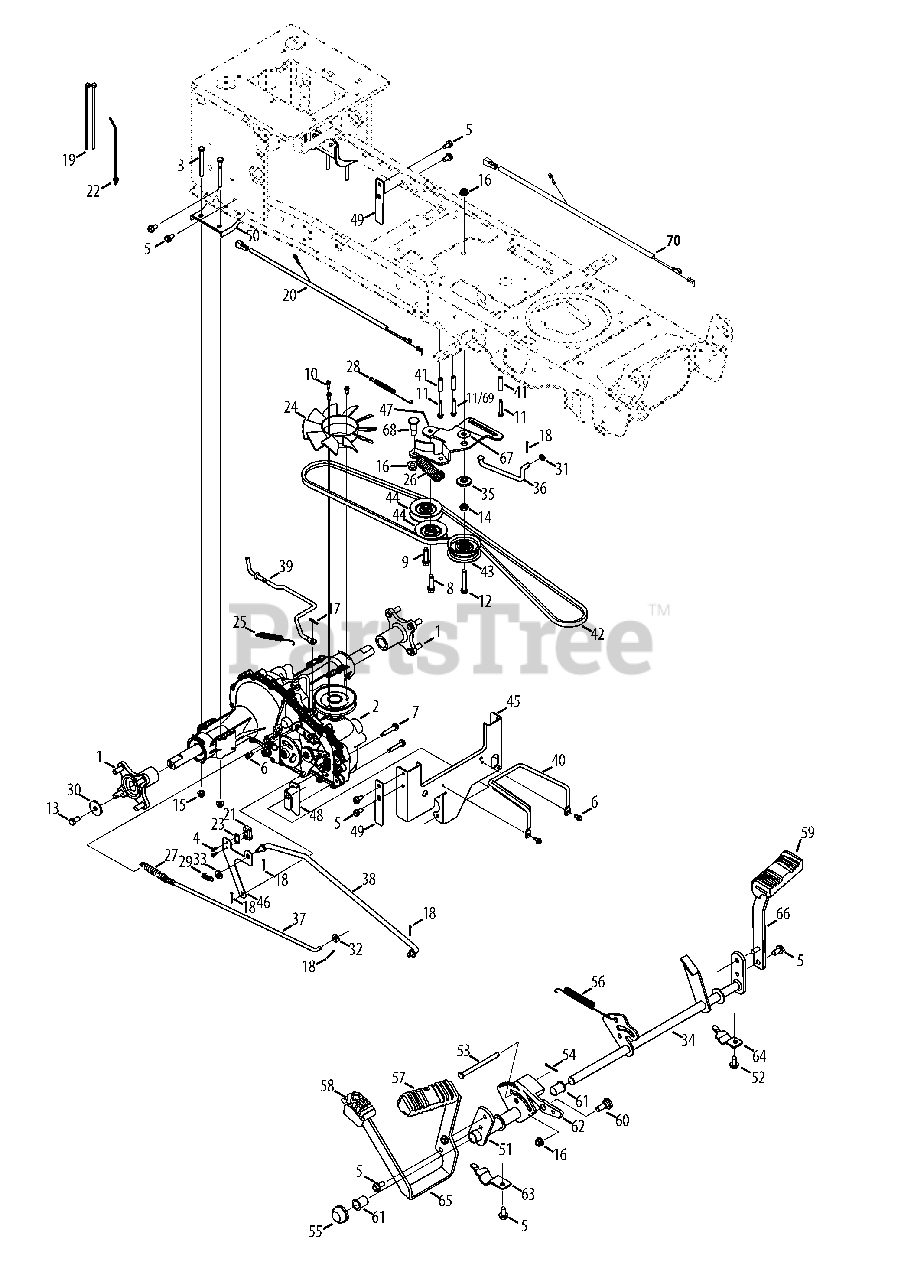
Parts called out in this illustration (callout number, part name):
1	Wheel Assembly Hub
2	Transmission
3	Hex Screw, 5/16-18:3.00
4	Screw, #8-18:0.500
5	Taptite Screw, 5/16-18:.750
6	Taptite Screw, 1/4-20:0.500
7	Taptite Screw, 5/16-18:1.750
8	Taptite Sems Screw, 3/8-16:1.500
9	Taptite Sems Screw, 3/8-16:1.875
10	Screw, #12-24:0.625
11	Taptite Screw, 1/4-20:1.625
12	Hex Screw, 3/8-16:2.25
13	Hex Screw, 3/8-16:.750
14	Jam Nut, 7/16-20
15	Flangelock Nut, 5/16-18
16	Flangelock Nut, 3/8-16
17	Cotter Pin, .072 DIA. x 1.13 LG
18	Cotter Pin, 3/32:1.0
19	Cable Tie, 3/16 x .05 x 7.4
20	Jumper Harness
21	Short Spring Switch
22	Push Mount Cable Tie 7.5 LG
23	Insulator Nut Plate
25	Extension Spring, .50 DIA x 5.0 LG
26	Extension Spring, 1.00 DIA x 4.75
27	Extension Spring, .59 OD x 4.00 LG
28	Extension Spring, .38 DIA x 5.6
29	Extension Spring, .375 OD x 1.44 LG
30	Flat Washer, .390 x 1.500 x .134
31	Flat Washer, .330 x .630 x .0635
32	Flat Washer, .344 x .750 x .120
33	Flat Washer, .407 x .812 x .135
34	Brake Control Assembly
35	Shoulder Spacer, 1.375 x .380 x .183
36	Footpedal Bypass Transmission Rod
38	Control Rod
39	Disengage Rod
40	Belt Keeper, 5/16
41	Spacer, 260 x .372 x 1.420 LG
42	V Belt, 4L x 77.0
43	Flat Idler Pulley, 2.75 OD
44	V Idler Pulley, 3.06
45	Torque Bracket
46	Switch Bracket
47	Center Idler Bracket
49	Plate Bracket
51	Hydro Pedal Bracket Assembly
52	Taptite Screw, 5/16-18:0.625
53	Clevis Pin, 5/16 x 3.985
54	Bow-Tie Cotter Pin
56	Extension Spring, .63 DIA x 4.95 LG
57	Pad, Pedal, Forward
58	Pad, Pedal, Reverse
59	Pad, Pedal, Brake
60	Shoulder Bolt, .500 x .270:3/8-16
61	Flange Bearing, .630 ID x .695 OD x .60
62	Cruise Latch
63	Pedal Support Bracket
64	Pedal Support Bracket, 5/8
65	Bracket, Pedal, Drive Hydro
66	Brake Pedal Bracket
67	Scr, Shldr, .50 x .685 3/8-16
68	Washer, Flat, .385 x 1.0 x .030
69	Taptite Screw, 1/4-20:1.75
70	Jumper Harness, Ground & Reverse
